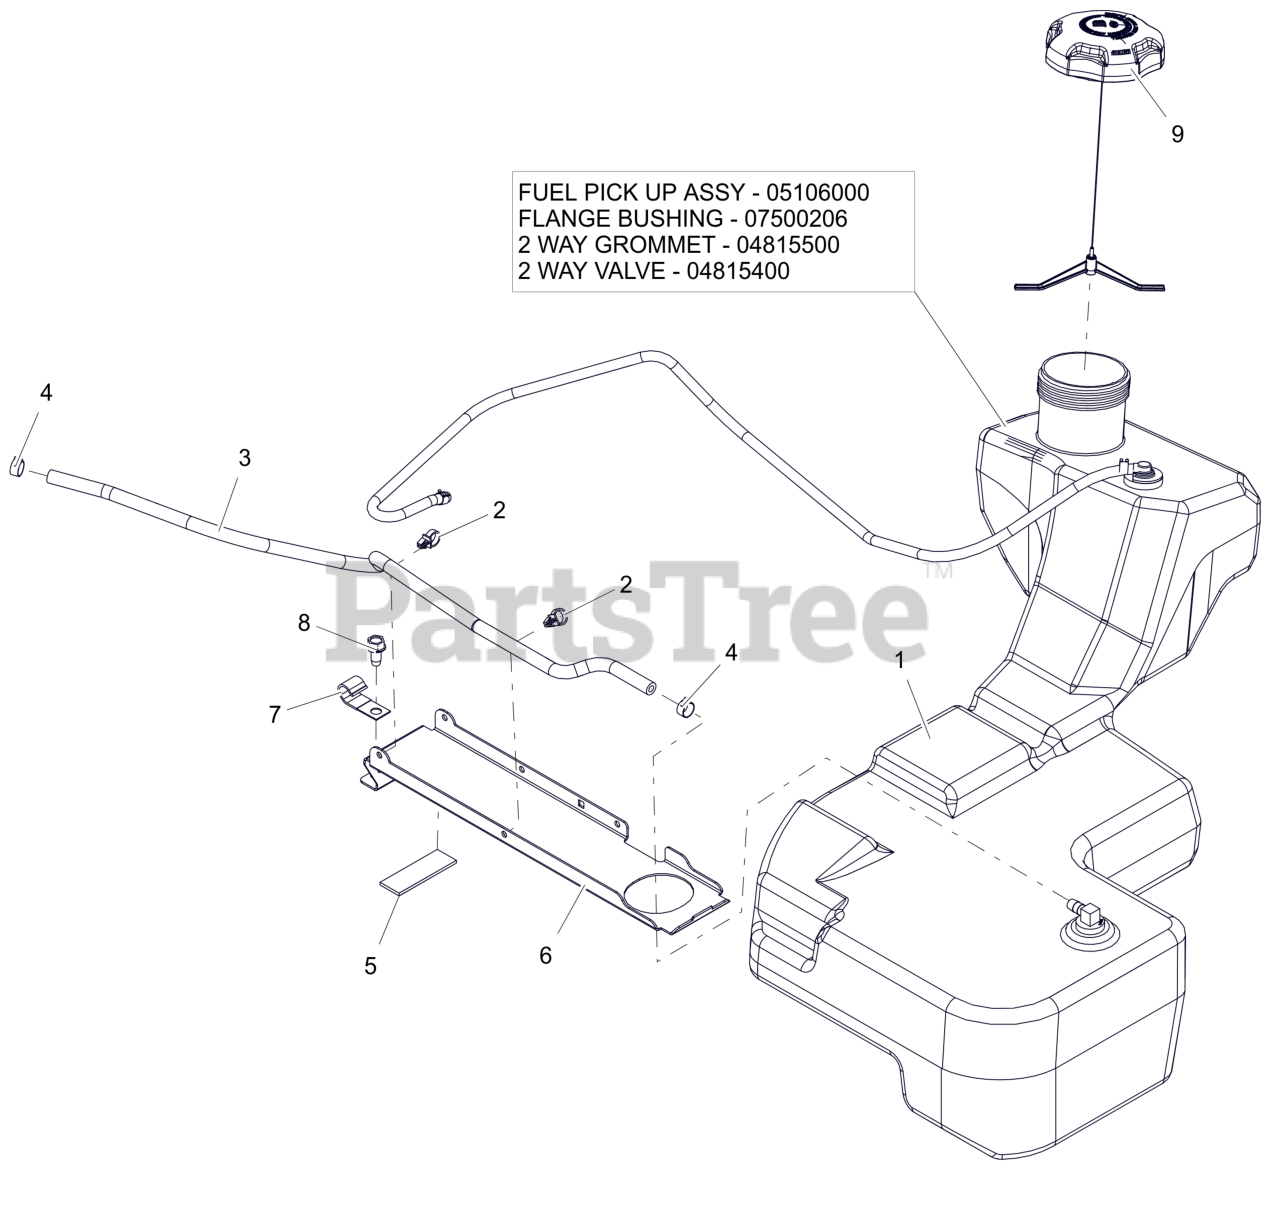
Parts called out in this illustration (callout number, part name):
1	ASM, FUEL TANK-HD
1	ASM, HD FUEL PICK-UP
1	BSHG-FLG .375X1.062X.625 NITR
1	GROMMET, 2-WAY
1	VALVE, 2-WAY
2	ROUTING CLIP (1/2" ID)
3	1 INCH OF HOSE, .25 LOW-PERM BULK GAS
4	CLAMP, FUEL LINE
5	PAD,RBR 1.0"X3.0" W/ADHESIVE
6	BRKT, FUEL TANK HOLD DOWN
8	SCR,TAP .375-16X.75 HWH TR ZCC
9	CAP, FUEL - 3.50 RATCHET INLET VENT
